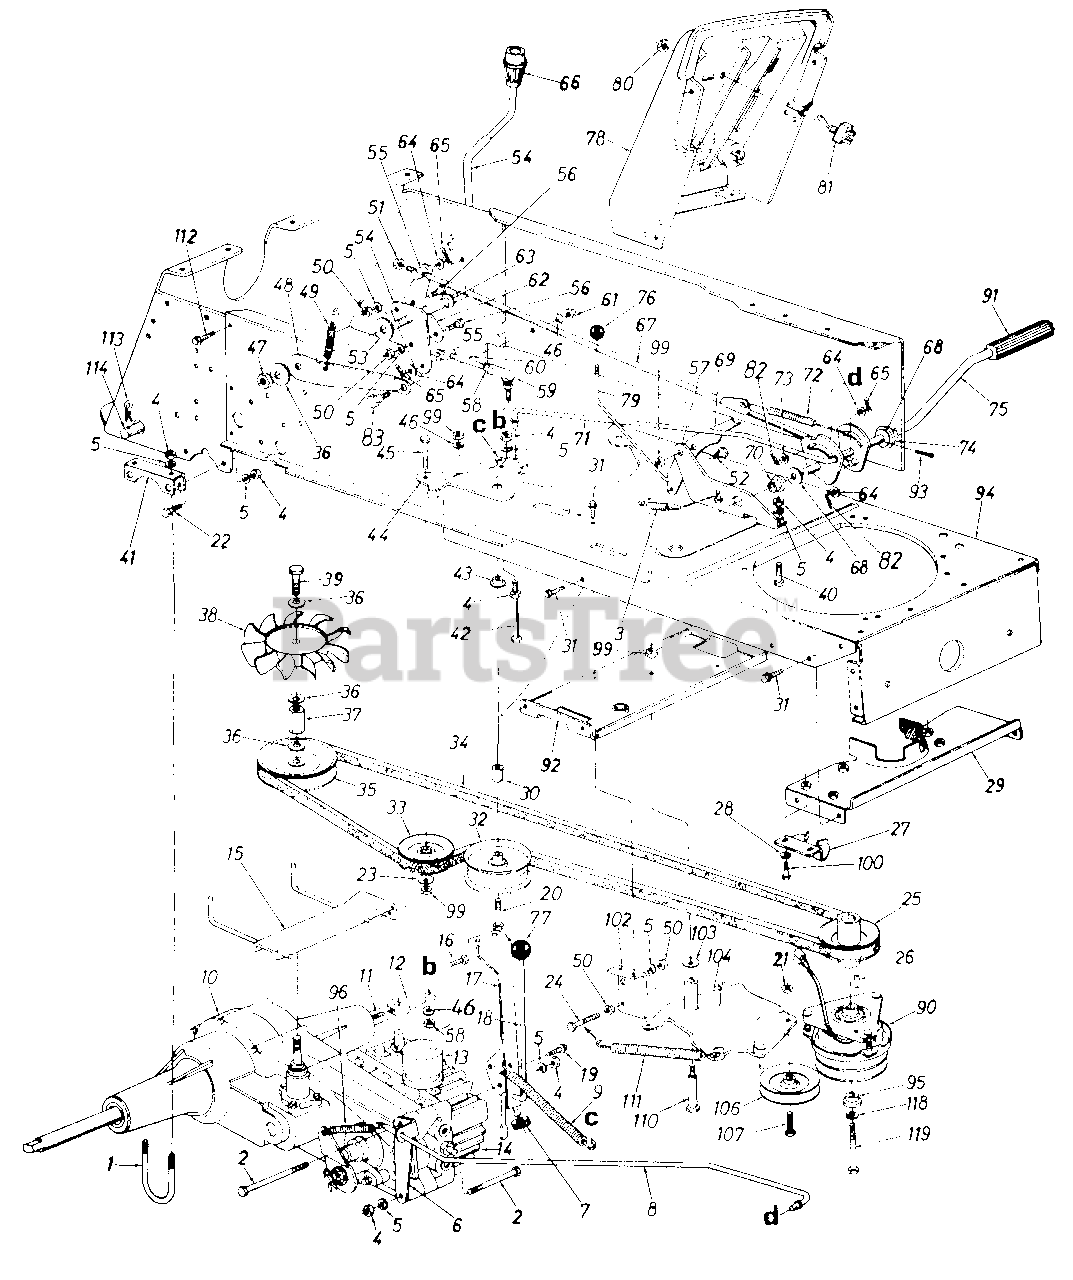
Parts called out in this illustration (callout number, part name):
1	U-Bolt 5/16-18 x 3.25" Lg.
2	Hex Patch Bolt 5/16-18 x 4.5" Lg. (Grade 5)
3	Ext. Spring .5" O.D. x 1.55"
4	Hex Nut 5/16-18 Thd.
5	L-Wash. 5/16" I.D.
6	Brake Rod Guide Brkt.
7	Rubber Wash. .33" I.D. x .87"
8	Brake Rod
9	Ext. Spring .62" O.D. x 6.12" Lg.
10	Transaxle
11	Set Screw 5/16-24 x .38" Lg.
12	Pintle Shift Lever
13	Reservoir
14	Hydrostatic Pump
15	Belt Guard Ass'y.
16	Hex Bolt 5/16-18 x 4.5" Lg. (Grade 5)
17	Transaxle Torque Bracket
18	Transaxle Control Rod
19	Hex Wash. Hd. B-Tap Scr. 5/1 6-1 8
20	Hex Bolt 3/8-16 x 2.75" Lg.
21	Hex Cent. Lock Nut 3/8-16 Thd.
22	Hex Bolt 5/16-18 x .75" Lg. (Grade 5)
23	Fl-Wash. .385" I.D. x .87" O.D.
24	Hex Bolt 5/16-24 x 1.75" Lg.
25	Engine Pulley
26	Sq. Key 1/4 x 1.5" Lg.
29	Belt Keeper Brkt. Ass'y.
30	Spacer .375" I.D. x .75" Lg.
31	Hex Wash. Hd. TT-Tap Scr. 1/4-20 x .5" Lg.
32	Fl-Idler Pulley 3.25" Dia.
33	V-Belt Idler
34	V-Belt
35	Transmission Pulley 4.25" O.D.
36	Bell-Wash. .56" I.D. x 1.5"
37	Fan Adapter Nut 9/16-18 Thd.
39	Hex Bolt 9/16-18 x .5" Lg.
40	Hex Bolt 5/16-18 x .75" Lg.
41	Transaxle Mtg. Bracket
42	Hex Bolt 5/16-18 x 2.75" Lg.
43	Shld. Spacer .625" I.D.
44	Clutch Idler Bracket
45	Hex Bolt 3/8-16 x 1.5" Lg.
46	L-Wash. 3/8" I.D.
47	Hex Jam Nut 1/2-20 Thd.
48	Speed Control Rod Torque Brkt.
49	Ext. Spring 2.5" Lg.
50	Hex Nut 5/16-24 Thd.
51	Hex Jam Nut 3/8-24 Thd.
52	Shld. Bolt .50" Dia. x .170"
53	Fiber Washer .54" I.D. x 1.75"
54	Speed Control Handle Ass'y.
55	Ferrule 3/8-24 Thd.
56	Hex Bolt 5/16-24 x .62" Lg.
57	Foot Pedal Mtg. Brkt.
58	Hex Nut 3/8-24 Thd.
59	Ball Joint Ass'y.
60	Control Rod 3/8-24 x 3.75" Lg.
61	Hex Nut 3/8-16 Thd.
62	Speed Selector Handle Brkt.
63	Fl-Wash. .531" I.D. x 1.25" O.D.
64	Fl-Wash. .385" I.D. x .62" O.D.
65	Internal Cotter Pin
66	Shift Knob
67	Neutral Return Rod
68	Fl-Wash. .64" I.D. x 1.24" O.D.
69	Parking Brake Lock Brkt.
70	Hex Flange Brg. .634" Dia.
71	Clutch Idler Rod
72	Extension Spring 8" Lg.
73	Fl-Wash. .344" I.D. x .62" O.D.
74	Flange Bearing w/Flats
75	Foot Pedal Ass'y.
76	Ball Knob Brake
77	Ball Knob 1/4-20 Thd.
78	Dash Panel Ass'y.
79	Parking Brake Link
80	Hex Nut 1/2-27 Thd.
81	Toggle Switch
82	Cotter Pin 3/32" Dia. x 1.0" Lg.
83	Shld. Bolt .5" Dia. x .212"
90	Electric Clutch
91	Foot Pad
92	Deck Idler Support Brkt.
93	Cotter Pin 1/8" Dia.
94	Lower Frame
95	Shoulder Spacer
96	Ext. Spring 3.675" Lg.
99	Hex Cent. L-Nut 3/8-16 Thd.
100	Hex Bolt 5/16-18 x .75" Lg. (Grade 5)
102	Parking Brake Mtg. Brkt.
103	Bell-Wash. .380" I.D. x .88" O.D.
104	Idler Brkt. Deck Ass'y.
106	V-Belt Idler
107	Hex Bolt 3/8-24 x 1.5" Lg.
110	Shld. Bolt .498" Dia. x 2.05"
111	Ext. Spring 4.0" Lg.
112	Hex Wash. AB-Tap Scr. 5/16 x .75" Lg.
113	Hitch Pin Clip
114	Hitch Rod
118	L-Wash. 7/16" I.D.
119	Hex Bolt 7/16-20 x 3.75" Lg.
